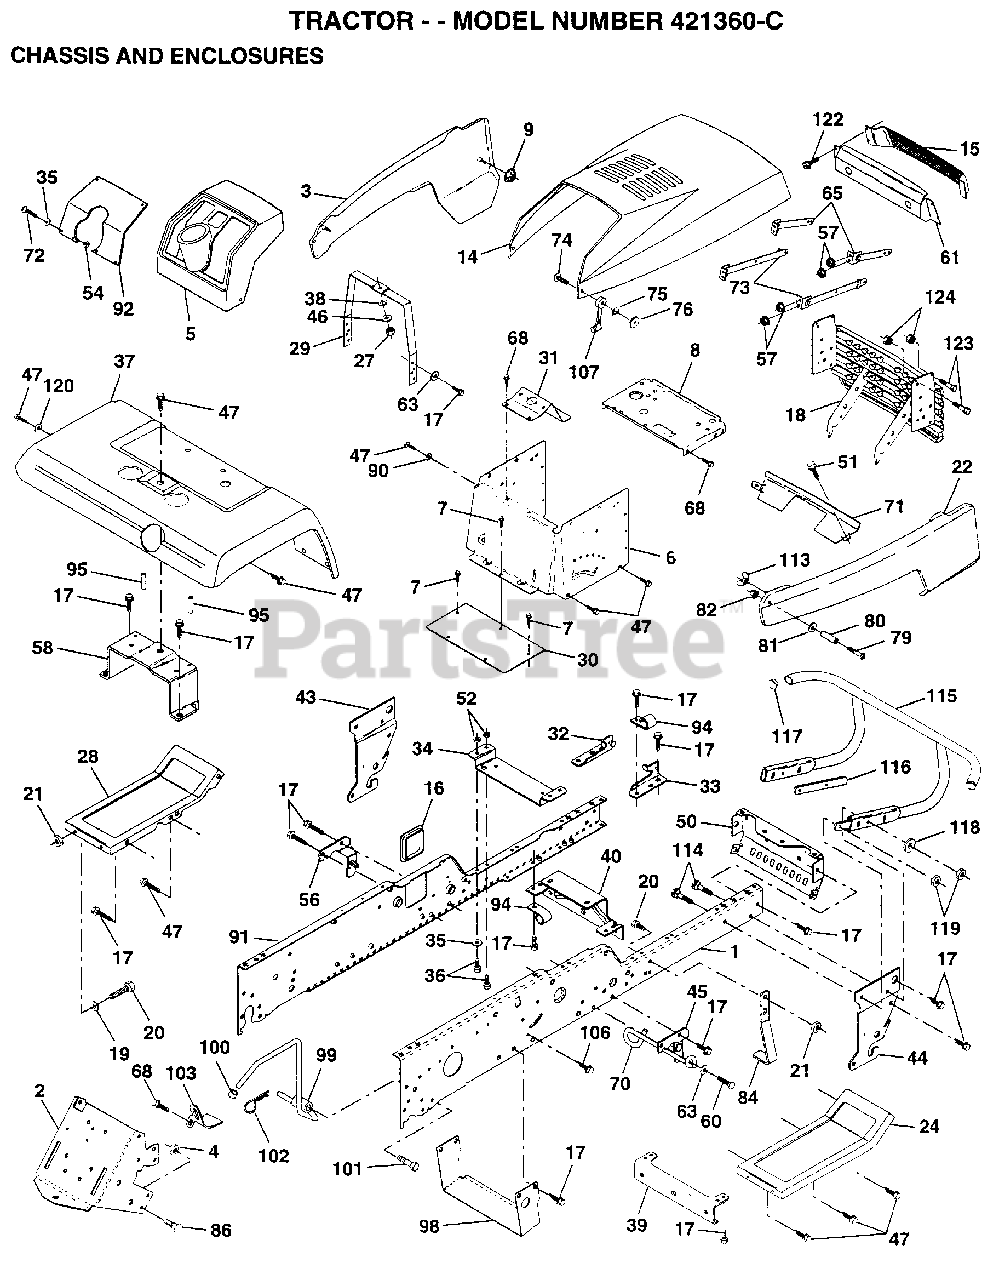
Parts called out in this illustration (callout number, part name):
2	DRAWBAR GT
4	NUT.7/16
5	DASHBOARD BLACK
6	DASH.1PC.LOWER
7	SCREW
8	SUPPORT.DASH.BTRY
9	PAL NUT LT
15	LENS.BAR.CLEAR
16	COVER ACCESS
17	SCREW
19	WASHER
20	BOLT
21	NUT
22	PANEL SIDE RH
24	FOOTREST.RH.LT/GT
28	FOOTREST.LH.LT/GT
29	DASH.SUPT.YP/HUSQ
30	SADDLE.HYDRO.95
31	BRAKET.SUPT.STEER
32	BRACKET ASM FRAME
33	BRACKET ASM FRAME
34	BRACKET.ENG.SUPT.
35	WASHER
36	BOLT
37	FENDER.PNT.
38	WASHER PM
39	BRACKET.AXLE.FRT.
43	BRACKET.SUS.FT.LH
44	BRACKET.SUS.FT.RH
46	LOCKWASHER
47	SCREW LT
50	BRACKET.CHASSIS.
51	SCREW CRT
58	BRKT.ASM.FENDER
60	SCREW
63	WASHER
68	SCREW LT
70	GUIDE.BELT.MID.SP
71	STRAP.GRILLE.PNT.
72	SCREW
74	SCREW
75	LOCKWASHER
76	WELDNUT
79	SCREW
80	SPACER LT
81	WASHER
84	STOP.OVER.CENTER
86	BOLT
90	LOCKWASHER
92	PLATE YP SLKSCR
94	CLIP GTV
95	NUT-PUSH YT
98	BRACKET SKID CHAS
99	ROD BYPASS
101	SCREW LT
102	RETAINER M
103	LOCK BYPASS BRKT
107	HOOD LATCH T
114	BOLT.3/8-14X1.25
115	BUMPER.ASM.W/PY
116	BRACKET.EXT.BUMP.
117	PLUG.PLASTIC
118	WASHER
120	WASHER HYT
124	NUT
